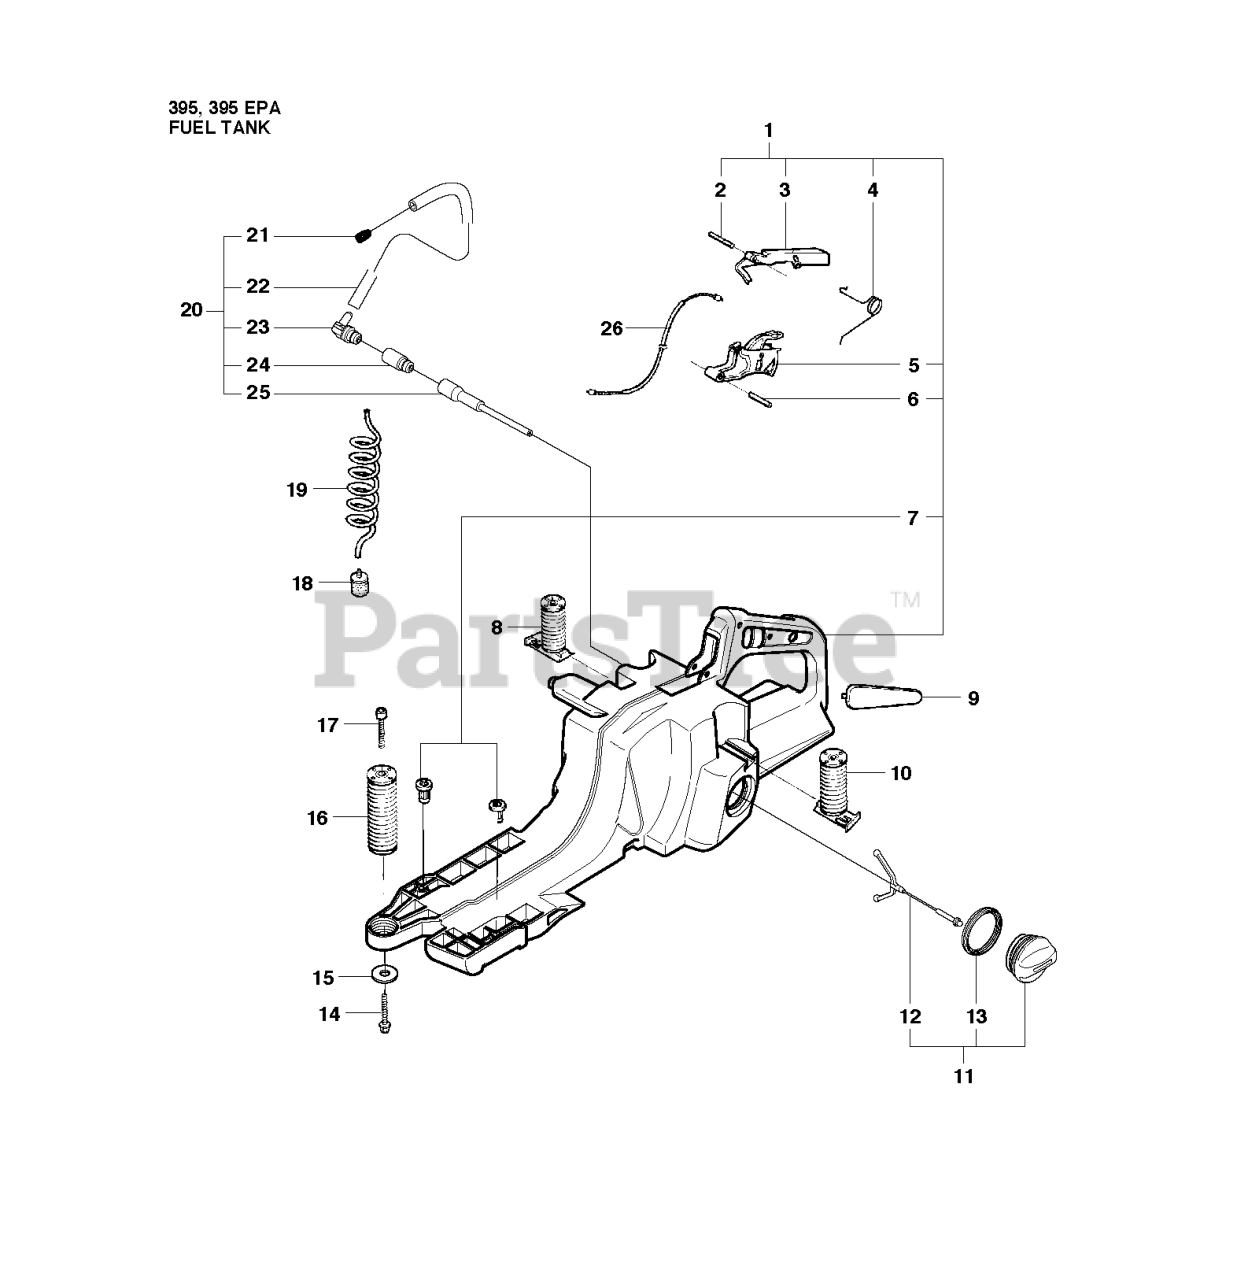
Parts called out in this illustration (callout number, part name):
2	PIN 3X25
3	THROTTLE CATCH
5	THROTTLE TRIGGER
6	PIN CPH8 4X20
7	THREAD INSERT
8	ANTIVIBE ELEMENT HARD
10	ANTIVIBE ELEMENT
12	HOLDER
15	WASHER 5.3X15
16	SPRING FRONT
18	RP FUEL FILTER
19	FUEL HOSE SPIRAL 300
20	TANK VENT ASSY
21	SINTER PLUG
22	FUEL HOSE STRAIGHT 105
25	TANK VALVE
